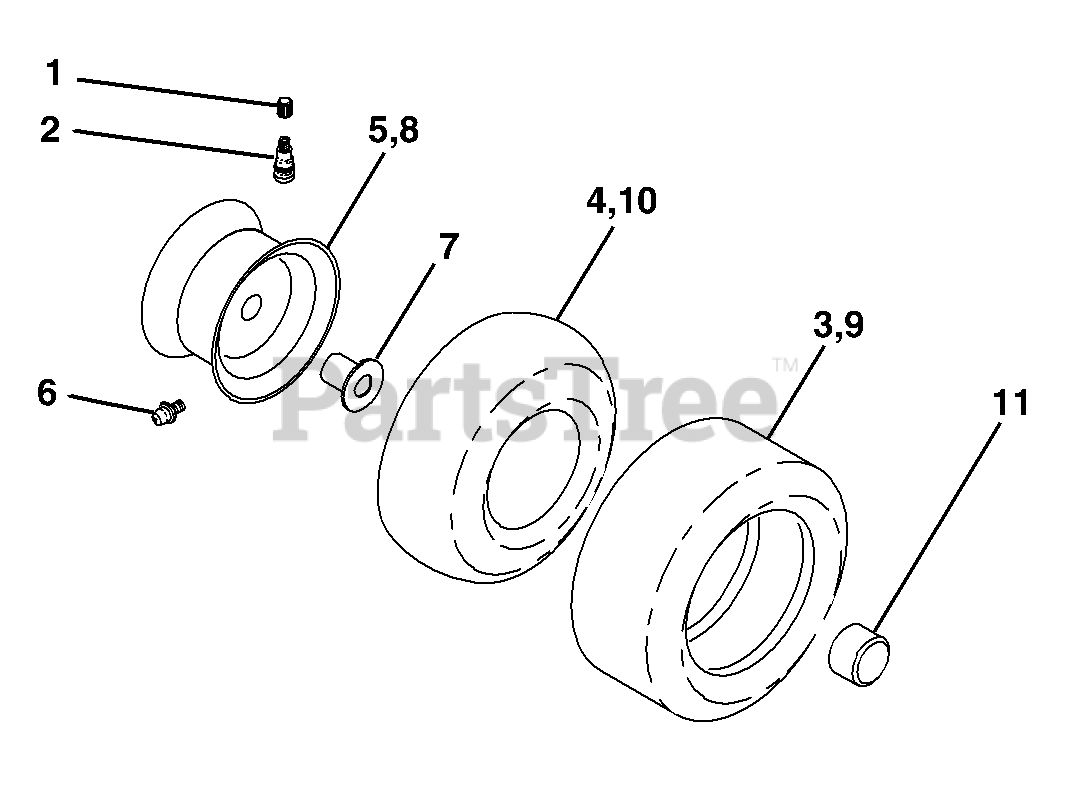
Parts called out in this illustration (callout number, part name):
1	Cap Valve Tire
2	Stem Valve
3	Tire F Ts 15 X 6 0 - 6 Service
4	Tube Front (Service Item Only)
5	Rim Asm 6" front Service
6	Fitting Grease (Front Wheel Only)
7	Bearing Flange (Front Wheel Only)
8	Rim Asm 8" rear Service
9	Tire R Ts 20X10.00-8 C Service
10	Tube Rear (Service Item Only)
11	Cap Axle Blk 1 50 X 1 00
